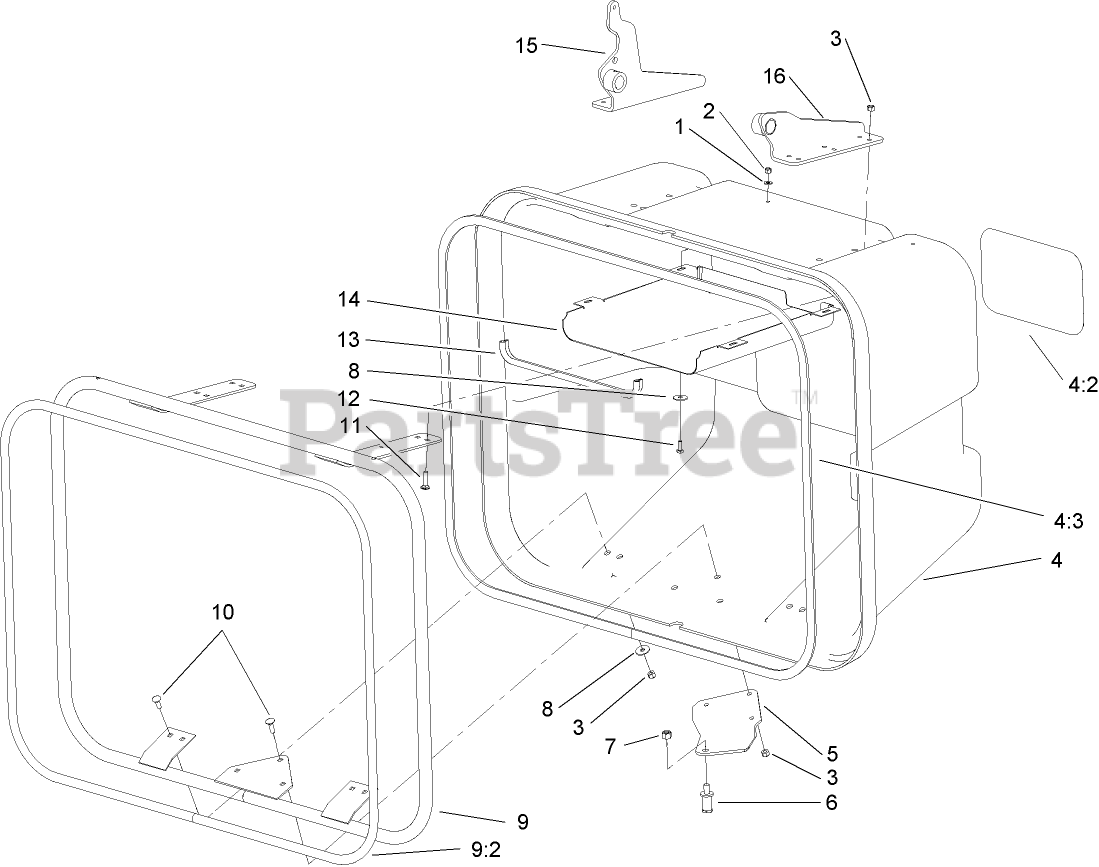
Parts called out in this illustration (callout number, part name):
1	WASHER-FLAT
2	NUT-LOCK, NI
3	NUT-LOCK, NI
4	DOOR ASM
4:2	DECAL
4:3	SEAL-HOPPER
5	BRACKET-LATCH, DOOR
6	BOLT-STRIKER
7	NUT-LOCK, NI
8	WASHER-FLAT
9	DOOR FRAME ASM
9:2	SEAL-HOPPER, ROUND
10	BOLT-CARR
11	SCREW-CARR
12	SCREW-HH
13	SEAL-TRIM
14	REAR SCREEN ASM
15	RH HINGE ASM
16	LH HINGE ASM
